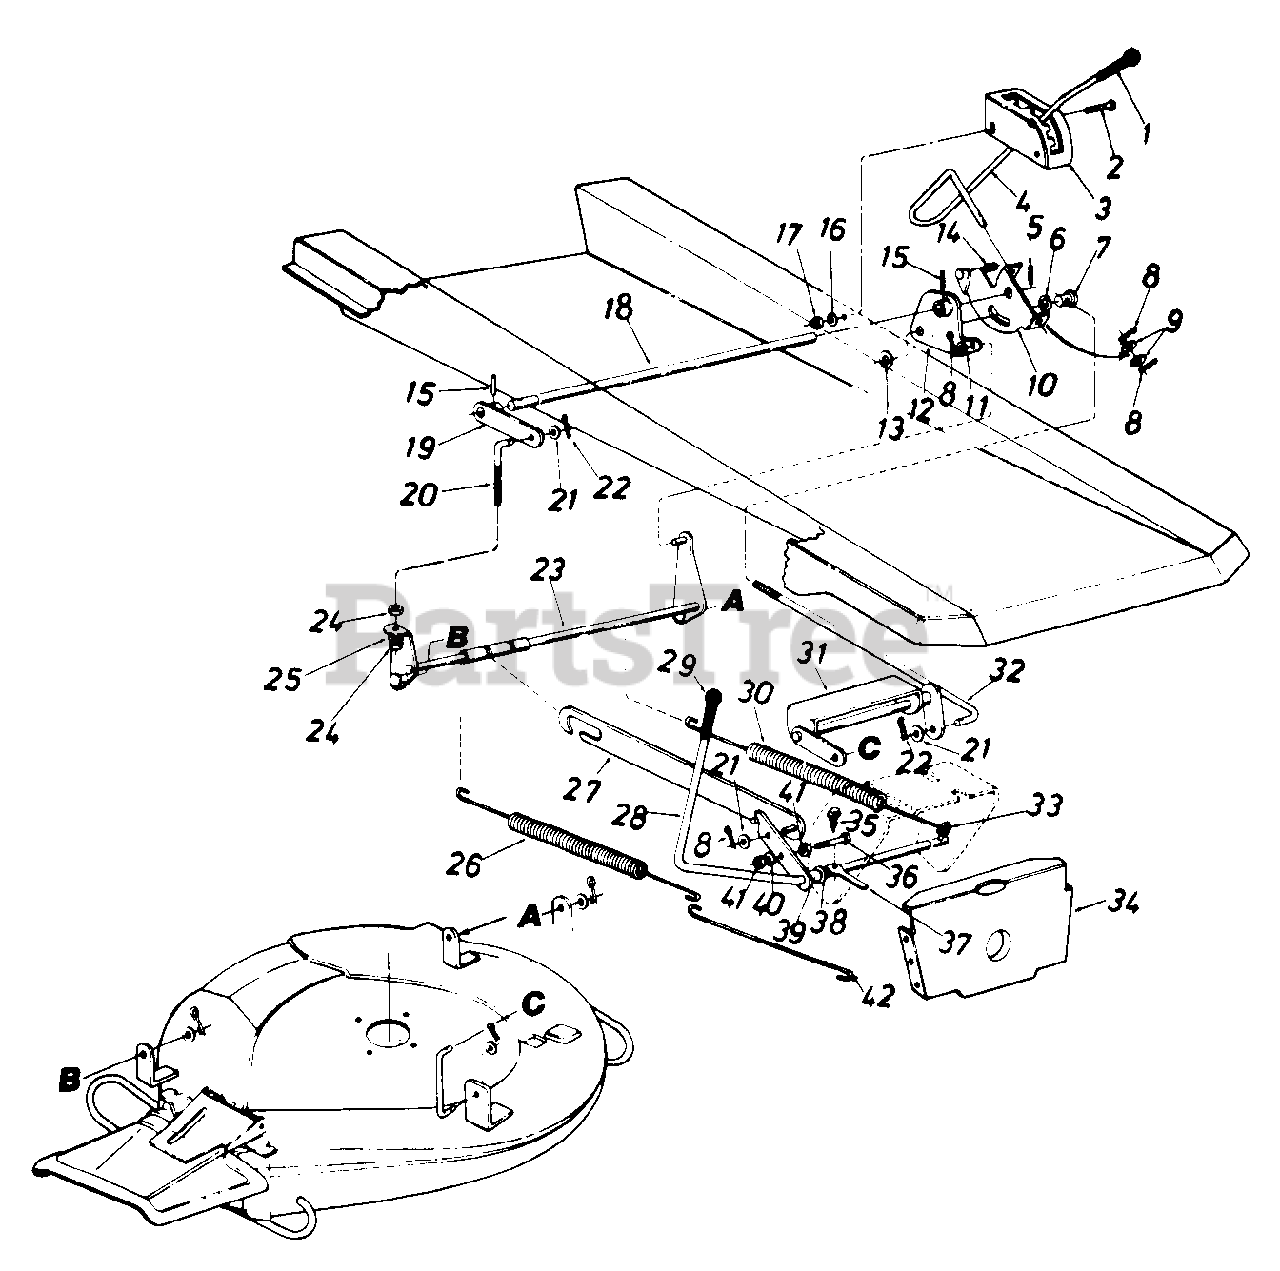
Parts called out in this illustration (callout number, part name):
2	SCREW-TRUSS MACH 5/16-18 X .75
5	PIN-SPRING SPIR 3/16 X 1.50
6	WASHER-FL-.640ID X 1.24OD X .06HDN
8	PIN-COTTER-1/8 DIA X 1.00
9	WASHER-FL-.531 X .930 OD X .050
10	RETAINER ASSY
11	WASHER-FL-.385 ID X .87 OD X .06
12	BRACKET ASSY-LIFT-LH
13	WASHER-FL-.635 ID X .93 OD
14	SPRING-COMPRESSION
15	PIN-SPRING SPIRAL 1/4X1.5 HEAVY DT
16	WASHER-LOCK-5/16
17	NUT-HEX 5/16-18
18	SHAFT-HGT ADJ-RR
19	BRACKET ASSY-LIFT-RH
20	SCREW-DECK ADJ 3/8-16 THD
21	WASHER-FL-.385 ID X .87 OD X .06
22	PIN-INTERN COT
23	LINK ASSY-RR
24	NUT-HEX 3/8-16
25	WASHER-LOCK-3/8
26	SPRING-EXTENSION
27	BRACKET ASSY-DECK DR
28	LEVER ASSY-BLADE ENG
30	SPRING-EXTENSION
31	LIFT ASSY-DECK-FR
32	ROD-CONNECTING
33	PIN-CLEVIS
34	BRACKET-PIVOT BAR
35	SCREW-HEX HD TAP 1/4-20 X 7.5
36	SCREW-HEX
37	ACTUATOR-SWITCH
38	WASHER-FL-.531 X .930 OD X .050
40	WASHER-LOCK-5/16
41	NUT-HEX 5/16-18
42	SPRING-HOOK
